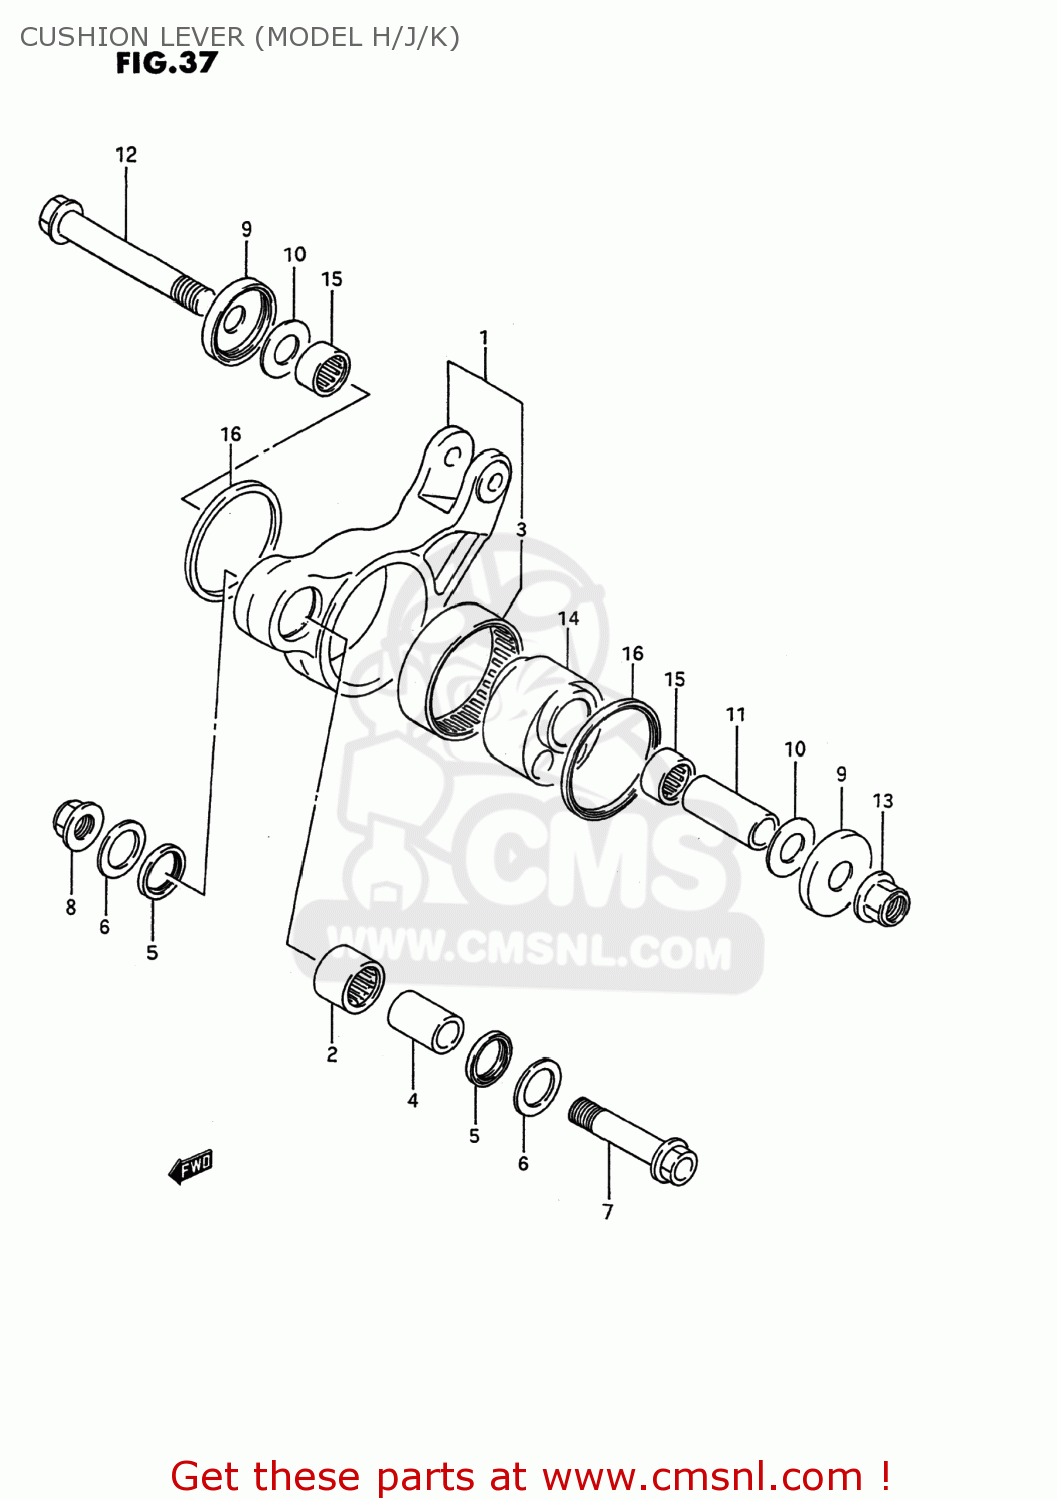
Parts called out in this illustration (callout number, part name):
1	LEVER SET,REAR CUSHION
2	BEARING(20X28X20)
3	BEARING(55X63X25)
4	SPACER,REAR CUSHION LEVER
5	SEAL,OIL(20X28X2.8)
6	WASHER
7	BOLT,RR CUSHION LEVER FR
8	NUT
9	DUST SEAL,RR C
10	WASHER
11	SPACER,RR CUSHION LEVER CTR
12	SHAFT,RR CUSHION LEVER
13	NUT
14	SPACER,REAR CUSHION ECCENTRIC
15	BEARING(20X27X20)
16	SEAL,RR CUSHION LEVER DUST
